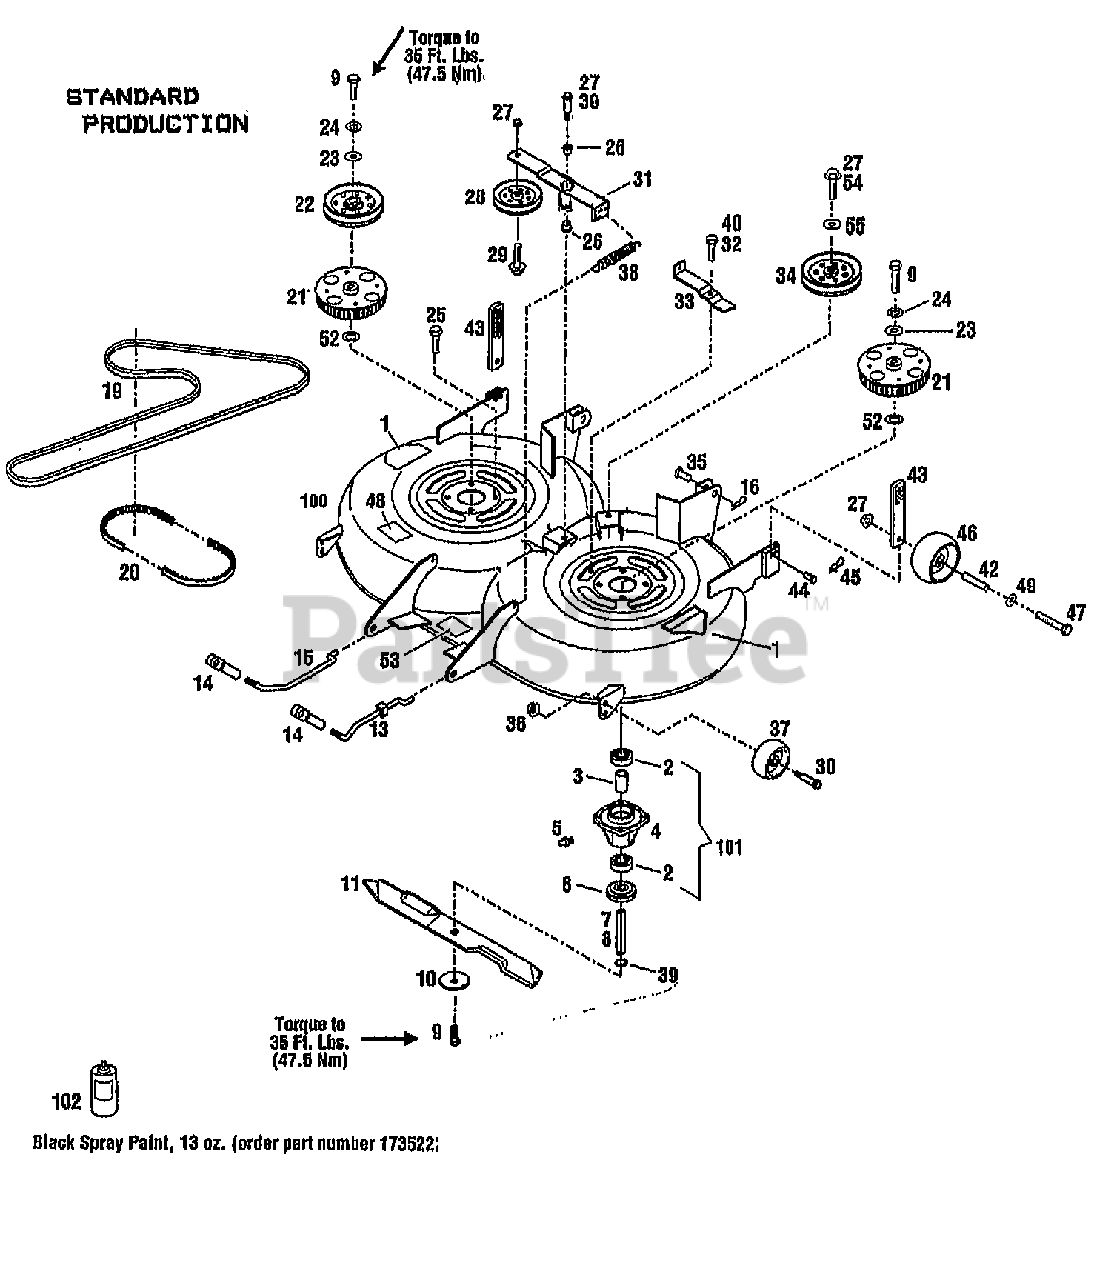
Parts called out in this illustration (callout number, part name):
1	DECAL-OPEI CAUTION
2	BEARING-BALL
4	HOUSING-SPINDLE
5	FITTING-GREASE 1/4-28X2.00
6	SPACER-BLADE
7	SHAFT-SPINDLE MED. H/T
8	SHAFT-SPINDLE LONG
9	SCR-HH 1/2-14X1.00
10	WASHER-BELLEVILLE
11	BLADE-MULCHING
13	ROD-LIFT FRONT LH
15	ROD-LIFT FRONT RH
16	PIN-HITCH .125X2.56 ZP
19	BELT-DRIVE PTO
20	BELT-DRIVE 38"
21	SPROCKET-56T GRIVORY
22	ASSM-SHEAVE DRIVE
23	WASHER-1.37X.453X.179 ZP
24	WASHER-LK .438 ZP
25	SCR-HFLK 5/16-18X.75
26	BUSHING-.5X.5 NYLON FLNG
27	NUT-HFLK 3/8-16 ZP
29	SCR-HFLK 3/8-16X1.75 G5ZP
30	SCR-SHLDR 3/8-16
31	ASSM-IDLER ARM
32	SCR-HHC 5/16-18X.75 GR 5 ZP
33	BRKT-BELT TENSION ADJ
35	PIN-CLEVIS .625X2.25
36	NUT-LOCK 3/8-16
37	WHEEL-GAGE
38	SPRING-EXTENSION
39	RING-RETAINING EXT .694 ID
40	NUT-TOP/LK 5/16-18 ZP
42	SPACER-GAGE WHEEL
43	LEVER-GAGE WHEEL ADJUST
44	PIN-CLEVIS .375 X .937 ZP
45	CLIP-HAIRPIN .07 DIA
46	WHEEL-GAGE
47	SCR-HH 3/8-16X3.5 G5 ZP
48	DECAL-BELT DRIVE
49	WASHER-.986X.437X.083 ZP
52	WASHER-THRUST .75 ID
53	DECAL-LIFT ROD
54	SCR-HH 3/8-16X2.50
55	WASHER-FLAT 3/8 SAE
100	DECK-MOWER W/DECALS
101	ASSM-MOWER SPINDLE
102	PAINT-BLACK SPRAY
